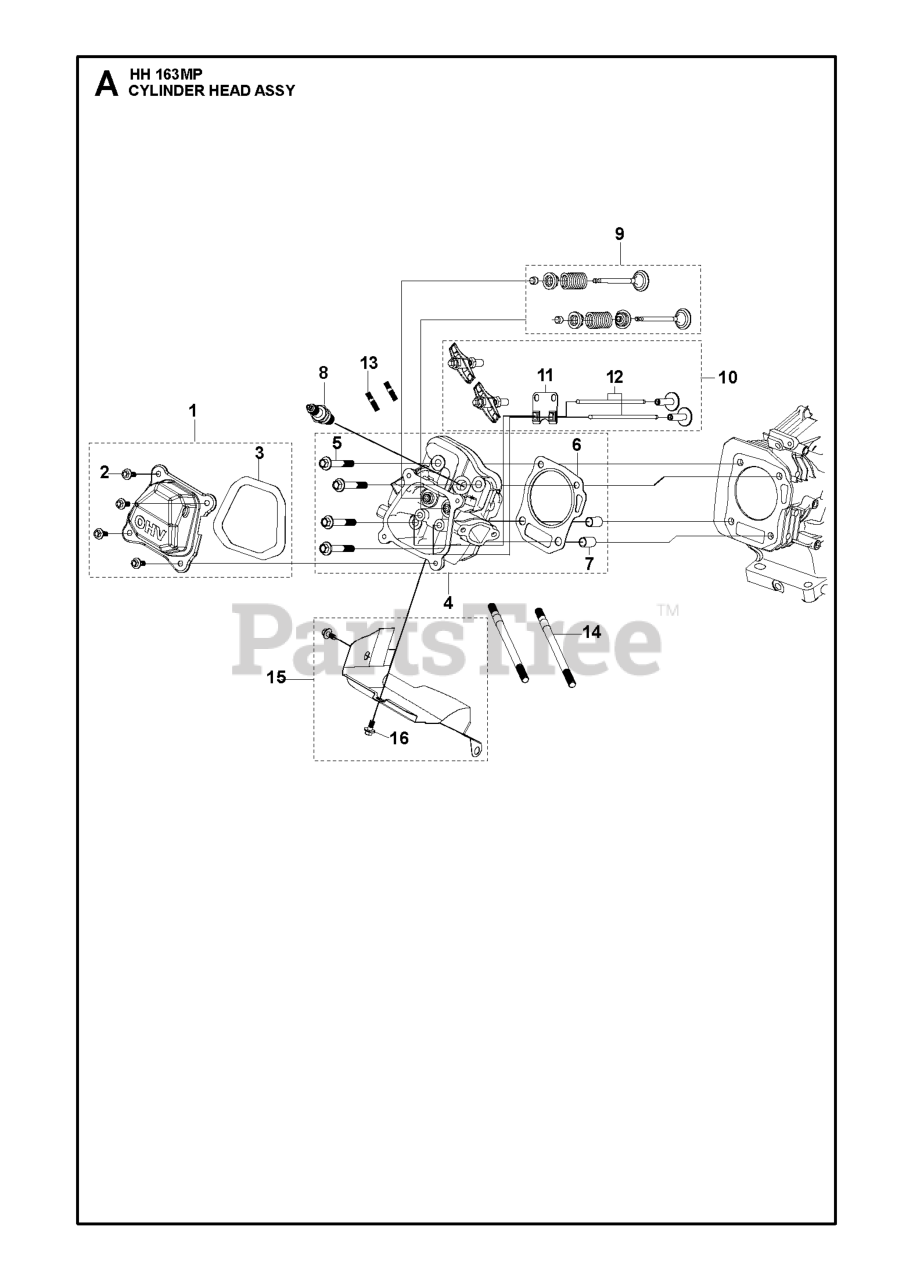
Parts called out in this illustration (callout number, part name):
2	Husqvarna TBD
7	PIN LOCATION PIN
8	SPARK PLUG HQT-7 RESISTOR
